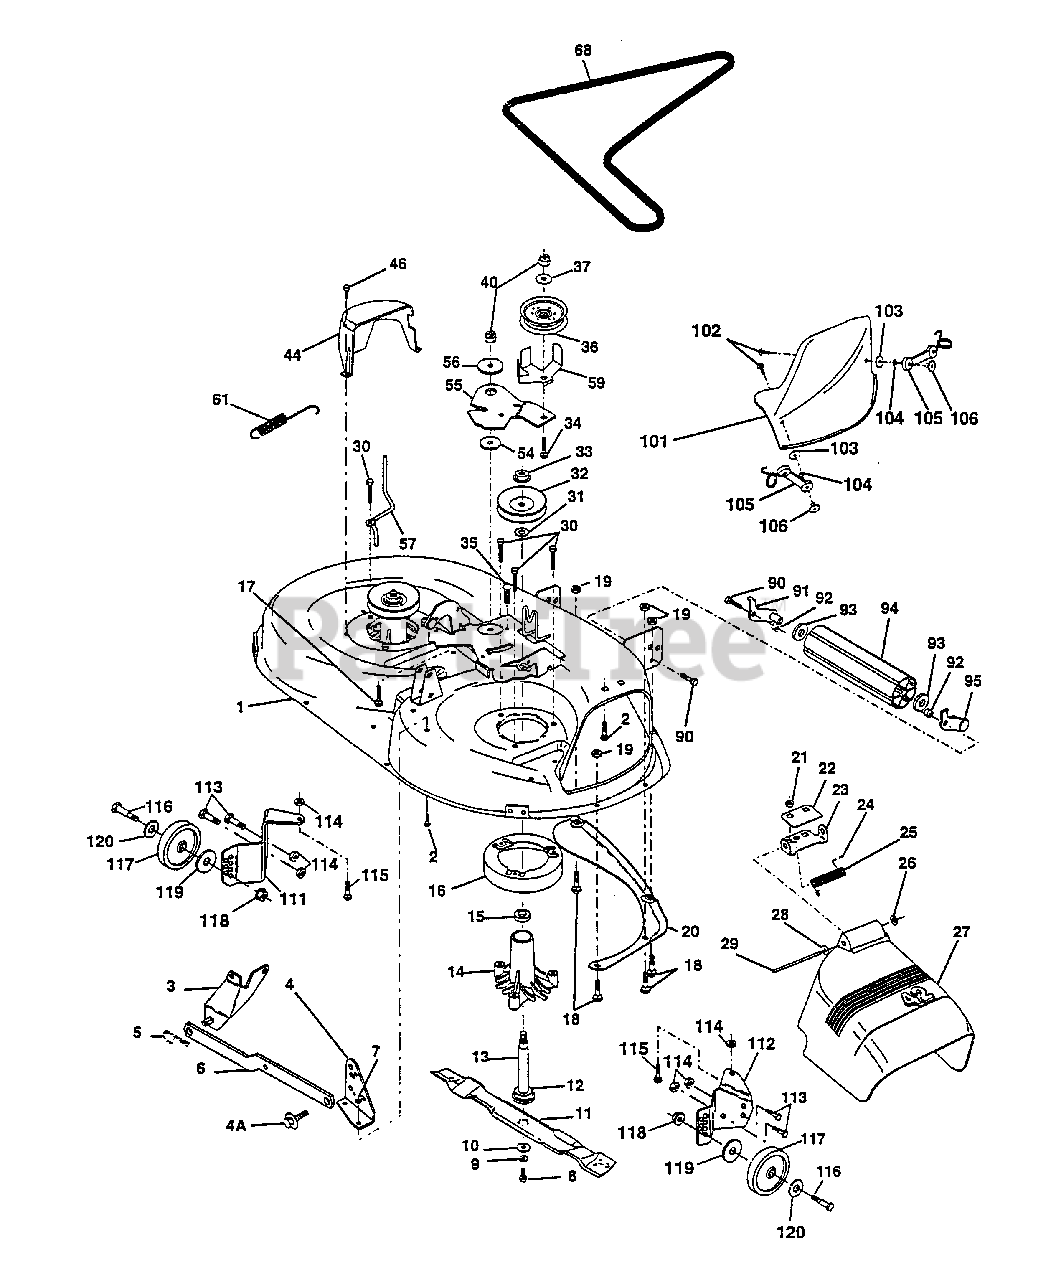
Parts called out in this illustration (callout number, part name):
1	Deck Asm MWR 42"weldment
2	Bolt Rdhd Sqnk 5/16-18unc X3/4
3	Bracket Asm Fr Sway Bar 38/42
4	Bracket Asm Deck 42"sway Bar
4A	Bolt Shoulder
5	Retainer Spring
6	Arm Suspension Rear
7	Locknut-hex W/ins 5/16-18unc P
8	Bolt 3/8-24x1 25 Gr8 Patched
9	Washer Lock Hvy 3/8 Unplated
10	Washer Hard Blade Mower Vented
11	Blade Mower Mulching 42"
12	Bearing Ball #6204 (Mandrel)
13	Shaft Asm W/lower Bearing
14	Housing Mandrel Vented(machd)
15	Bearing Ball Mandrel
16	Stripper Mower Vented
17	Bolt Rdhd Sqnk 3/8-16 X 2
18	Bolt Carr 5/16-18 X 5/8
19	Locknut-hex W/ins 5/16-18unc P
20	Baffle Vortex 42
21	Nut Lock 5/16-18
22	Stiffener Bracket 42"deck
23	Bracket Deflector Mower 42"
24	Cap Sleeve 80x 112 Blk Mower
25	Spring Torsion Deflector 2 52
26	Nut Push Phos & Oil
27	Shield Deflector Mower 42' Blk
28	Washer 11/32 X 5/8 X 16 Ga
29	Rod Hinge 42"6 75 WIg
30	Screw Thdrol Hex Hd Zinc Mwr.
31	Washer Spacer Mower Vented
32	Pulley Mandrel 42"
33	Nut 9/16top Lock Fing Cntr
34	Bolt Rdhd 3/8-16uncx2-3/4 Gr5
35	Fastner Christmas Tree
36	Pulley Idler Flat 3 060
37	Washer 13/32 X 13/16 X 16 Ga
40	Nut Lock 3/8-16 Unc
41	Spacer Spring Stop Idler
44	Guard Mandrel LH Black
46	Screw Thdrol 1/4-20x5/8
54	Washer Hardened
55	Arm Idler 42"mower LT/YT
56	Spacer Retainer Pm Mower
57	Guide, Belt
59	Guard, Belt
61	Spring Ext. Elect
68	V-Belt Mower 42"
90	Bolt Fin Hex 3/8-16unc X 1
91	Bracket Asm Noseroller LH
92	Nut Crownlock 3/8-16 Unc
93	Washer 17/32 X 7/8 X 16 Ga
94	Roller Nose 38 & 42
95	Bracket Asm Noseroller RH
101	Cover Mulching 42" Blk
102	Screw
103	Washer Lock #10
104	Washer #10
105	Latch Asm Bagger
106	Nut Weld .327/.304 #10-24
111	Bracket Wheel Guage Lh 42" Deck
112	Bracket Guage Wheel Rh 42" Deck
113	Bolt Hex Hd 5/16 - 18 UNC x 3/4
114	Nut Keps 5/16 - 18 UNC
115	Bolt Carriage 5/16 - Unc x 1/2
116	Bolt Shld "A" 2.41 "B" 1.66
117	Wheel Gauge blk. 4.93
118	Nut Centerlock 3/8 - 16 UNC
119	Washer 3/8 x 7/8 x 14 Ga.
120	Washer 17/32 x 15/16 x 12 Ga.
